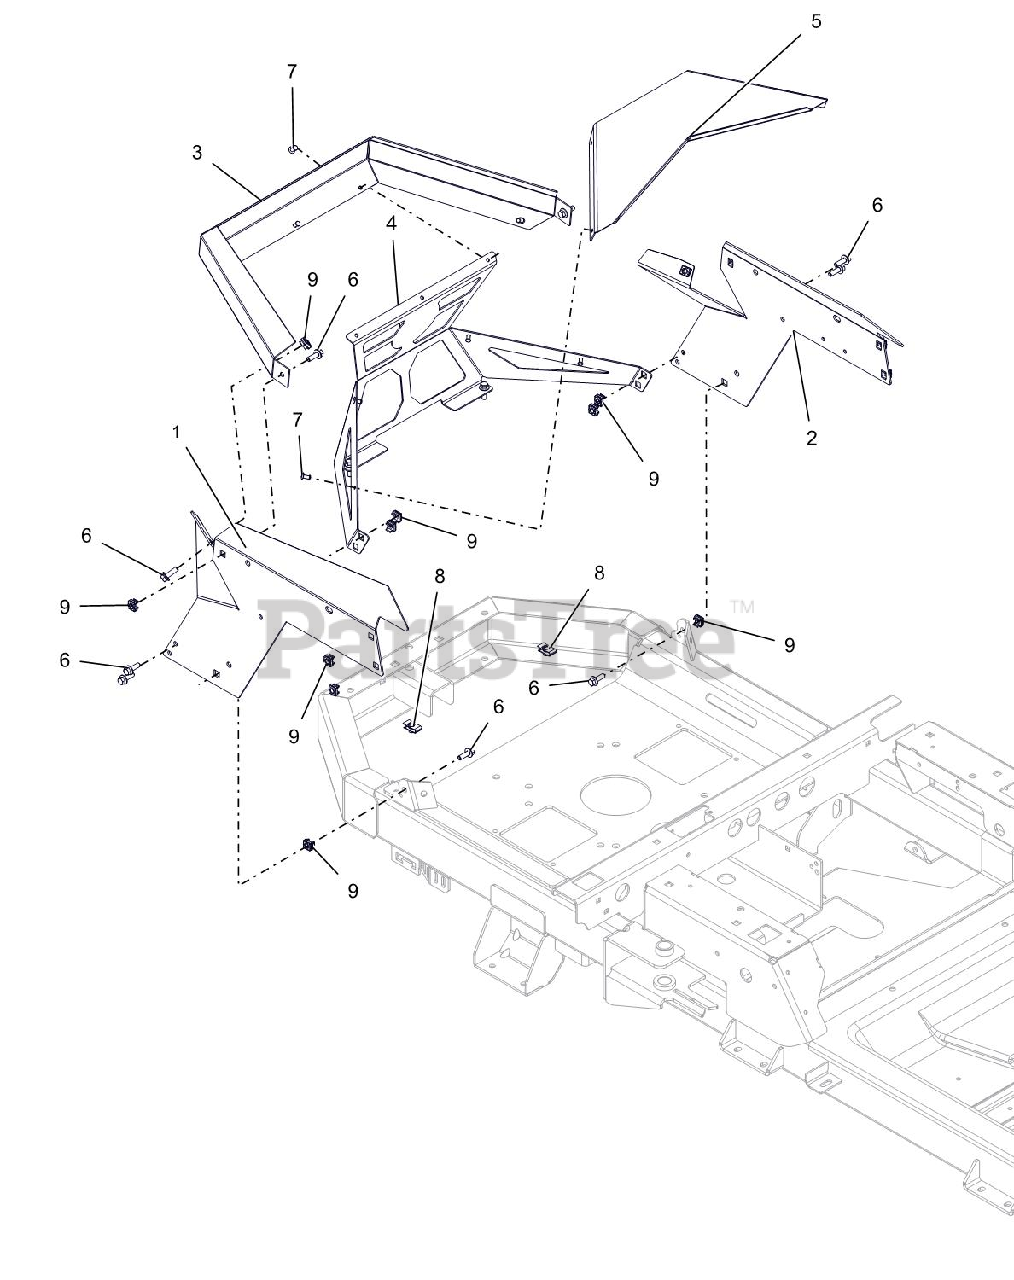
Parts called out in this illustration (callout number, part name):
1	PANEL, RIGHT REAR FENDER MOUNT
2	PANEL, LEFT REAR FENDER MOUNT
3	GUARD, ENGINE WRAP
4	GUARD, ENGINE
5	BAFFLE,ENGINE WRAP
6	BLT,HEX-FLG .25-20X.75 G5 BFP
7	RIVET, #66 STEEL POP PD BLACK
8	NUT-RTNR .25-20X.56
9	NUT RETNR .25-20
